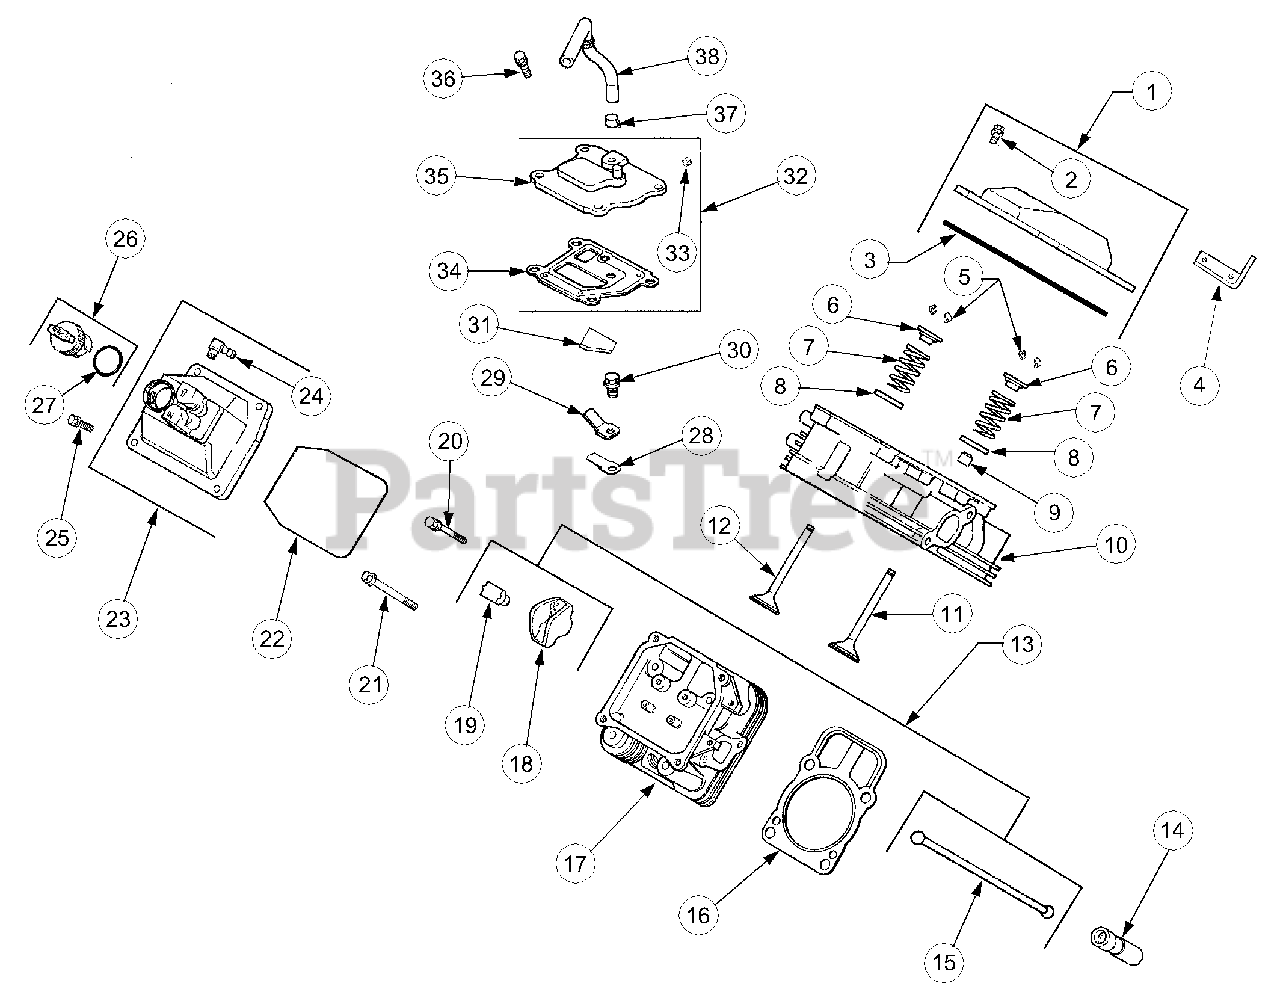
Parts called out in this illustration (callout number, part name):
1	Kit, Valve Cover
2	Screw, Shoulder
3	O-Ring, Valve Cover
4	Strap, Lifting
5	Kit, Retainer
6	Cap, Valve Spring
7	Spring, Valve
8	Retainer, Spring
9	Seal, Valve Stem
10	Head Assembly, #1 Cylinder
11	Valve, Intake Std
12	Valve, Exhaust Std
13	Kit, Valve Train
14	Lifter, Valve
16	Gasket, Cylinder Head
17	Head Assembly, #2 Cylinder
19	Pivot, Rocker Arm
20	Screw, Hex Flng, M6 x 1.0 x 34
21	Screw, Hex Flng, M10 x 1.5 x 90
22	O-Ring, Valve Cover
23	Cover, Fuel Pump Valve
24	Connector, 90°.
25	Screw, Shoulder
26	Cap Assembly, Oil Fill
27	O-Ring
28	Reed, Breather
29	Retainer, Breather Reed
30	Screw, Hex Flng, M5 x 0.8 x 10
31	Filter, Breather
32	Kit, Breather
33	Plug, Allen Hd 1/8 Pipe
34	Gasket, Breather
35	Cover, Breather
36	Screw, Hex Flng M6 x 1.0 x 20
37	Clamp, Breather
38	Hose, Breather
